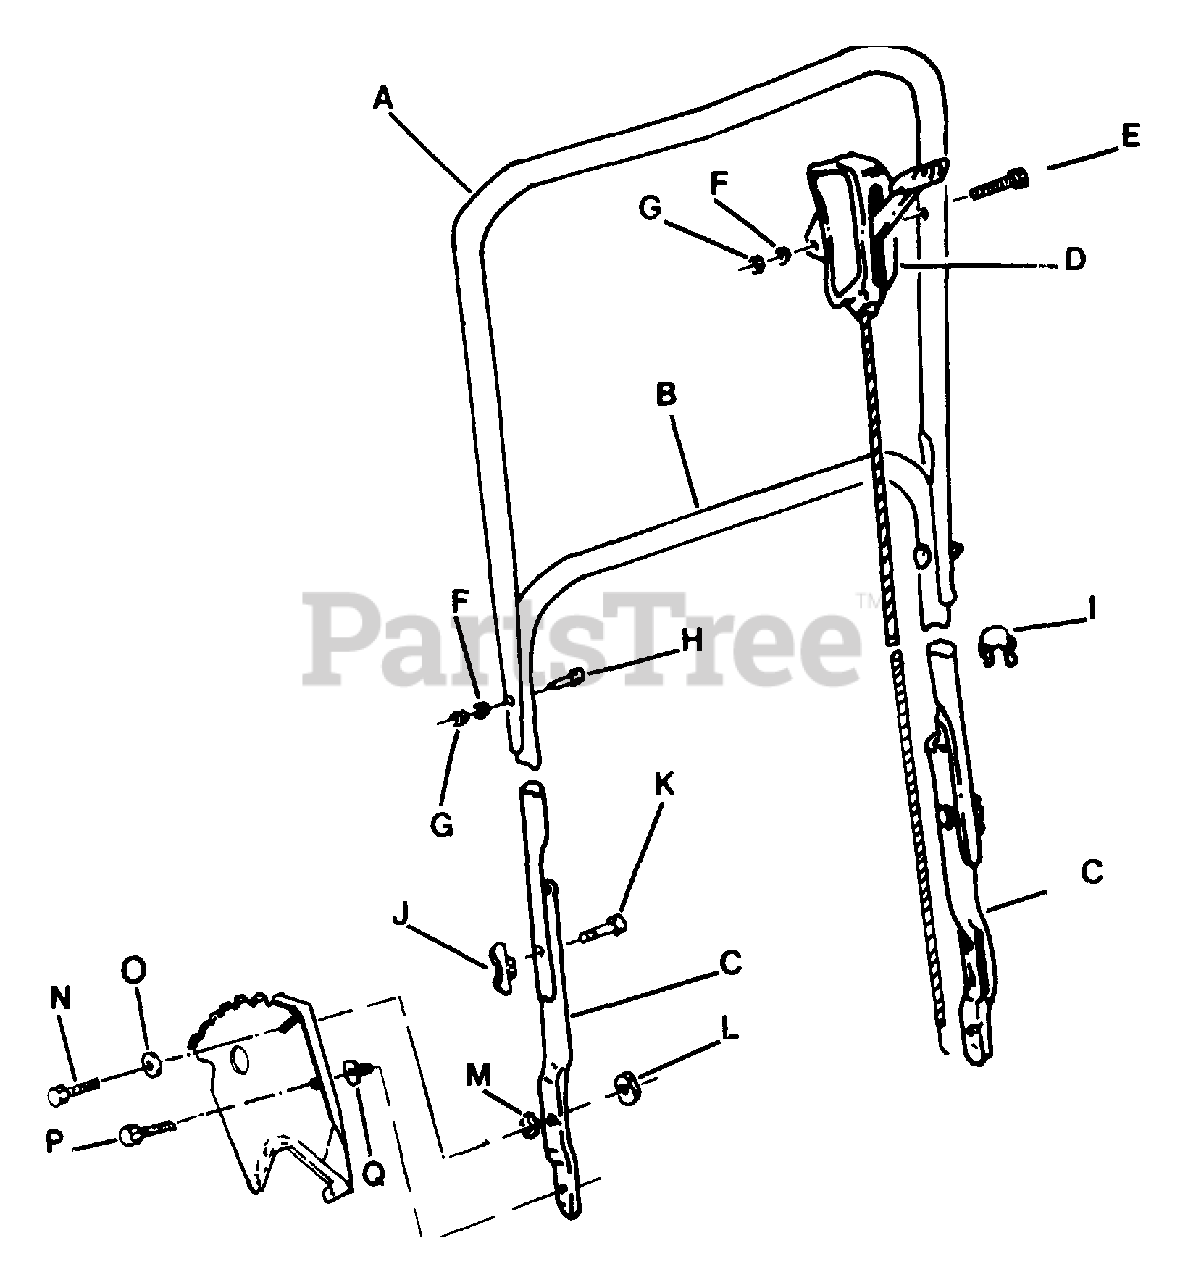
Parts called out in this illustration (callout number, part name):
A	HANDLE, UPPER
B	HANDLE, MIDDLE
C	HANDLE, LOWER
D	CONTROL, THROTTLE 46.5" (BRIGGS - STRATTON ENGINE)
D	CONTROL, THROTTLE 42.5" (TECUMSEH ENGINE)
E	SCREW, HEX HEAD CAP 1/4-28 x 1 3/4
F	WASHER, INTERNAL TOOTH LOCK 1/4
G	NUT, HEX 1/4-28
H	SCREW, HEX HEAD CAP 1/4-28 x 1 1/4
I	CLIP, THROTTLE CONTROL
J	NUT, WING
K	BOLT, CARRIAGE 1/4-20 x 1 3/4
L	NUT, WELD 5/16-24
M	WASHER, INT/EXT TOOTH LOCK 5/16
N	SCREW, HEX HEAD CAP 5/16-24 x 3/4
O	WASHER, FLAT SAE 5/16
P	SCREW, HEX HEAD CAP 5/16-18 x 5/8
Q	NUT, TEE 5/16-18
